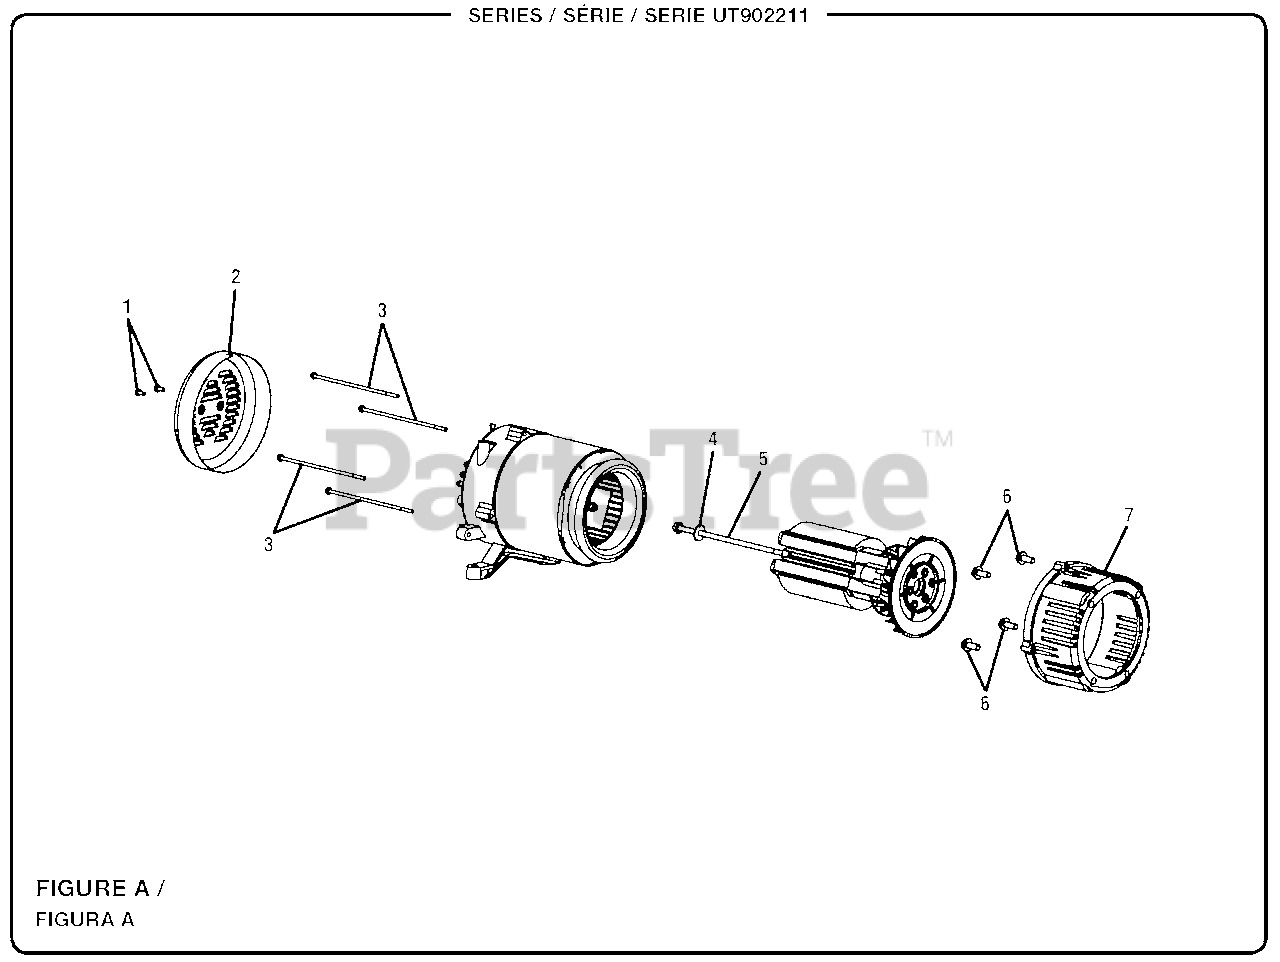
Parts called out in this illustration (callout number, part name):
2	Brush Cover
3	Bolt (1/4-20 x 6 in., Hex Hd.)
4	Lock Washer (5/16 in.)
5	Bolt (5/16-24 x 6-5/8 in., Hex. Hd.)
6	Bolt (3/8-16 x 1-1/4 in.)
7	Engine Adapter
